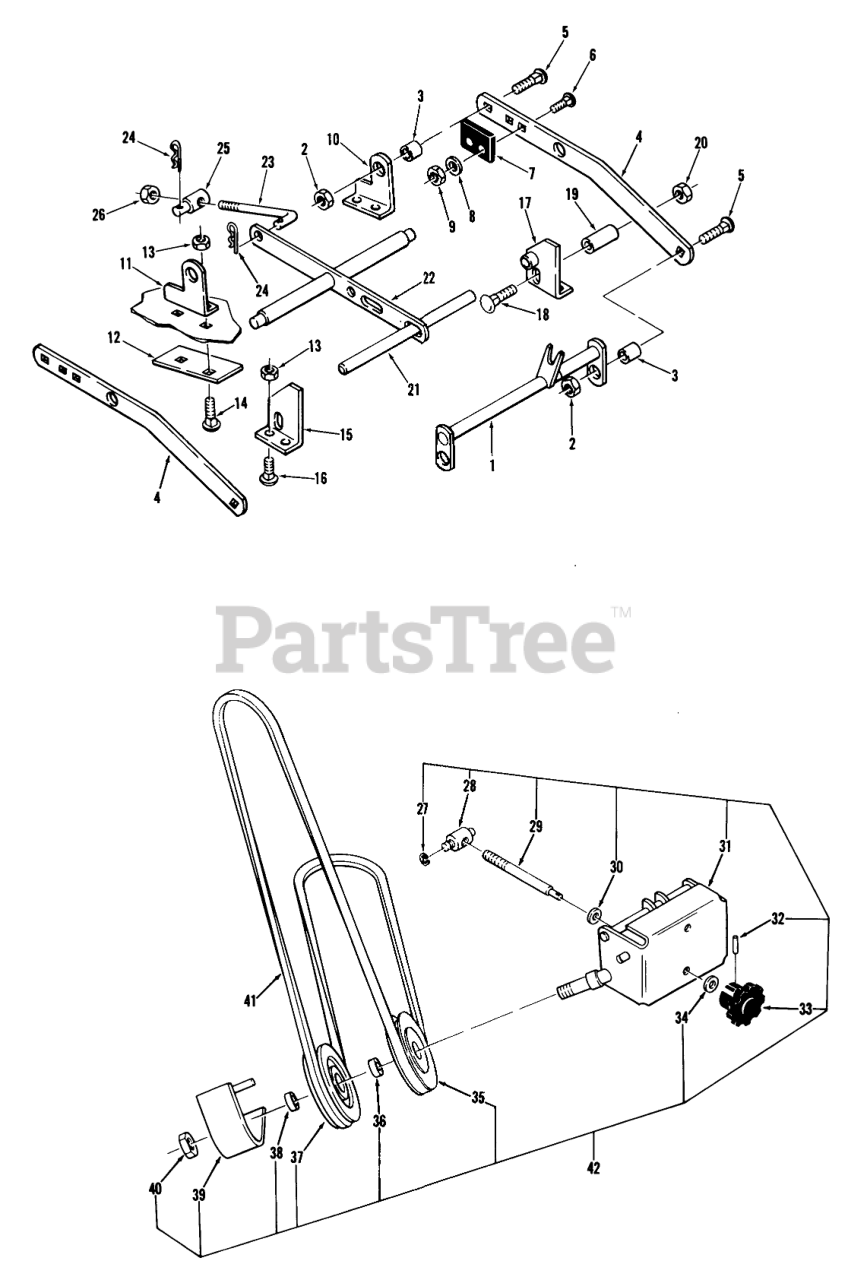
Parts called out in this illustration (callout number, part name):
1	Hitch
2	LOCKNUT-FLANGE
3	SPACER
4	Bar Draft
5	Bolt
6	Bolt-Carriage
7	BUMPER
8	Collar
9	Nut
10	L.H. Rear Bracket
11	R.H. Rear Bracket
12	Support Bracket
13	Nut
14	Bolt
15	Front Bracket RH
16	Bolt-Carriage
17	Front Bracket LH
18	CARRIAGE BOLT -4
19	SPACER-BEARING
20	Nut
21	Front Shaft
22	Leveler
23	ROD-LEVEL ADJUST
24	Hairpin
25	TRUNNION-LIFT
26	NUT
27	RING-RETAINING
28	TRUNNION-DOUBLE
29	ROD ADJ
30	Washer
31	Front Support
32	PIN-ROLL
33	KNOB-ADJUSTMENT
34	Washer
35	Pulley-V
36	SPACER
37	PULLEY-FLAT IDLER
38	SPACER-OUTER
39	Belt Cover
40	Nut 3/4-16 MF
41	V-BELT
42	ASM-SUPPORT,IDLER
